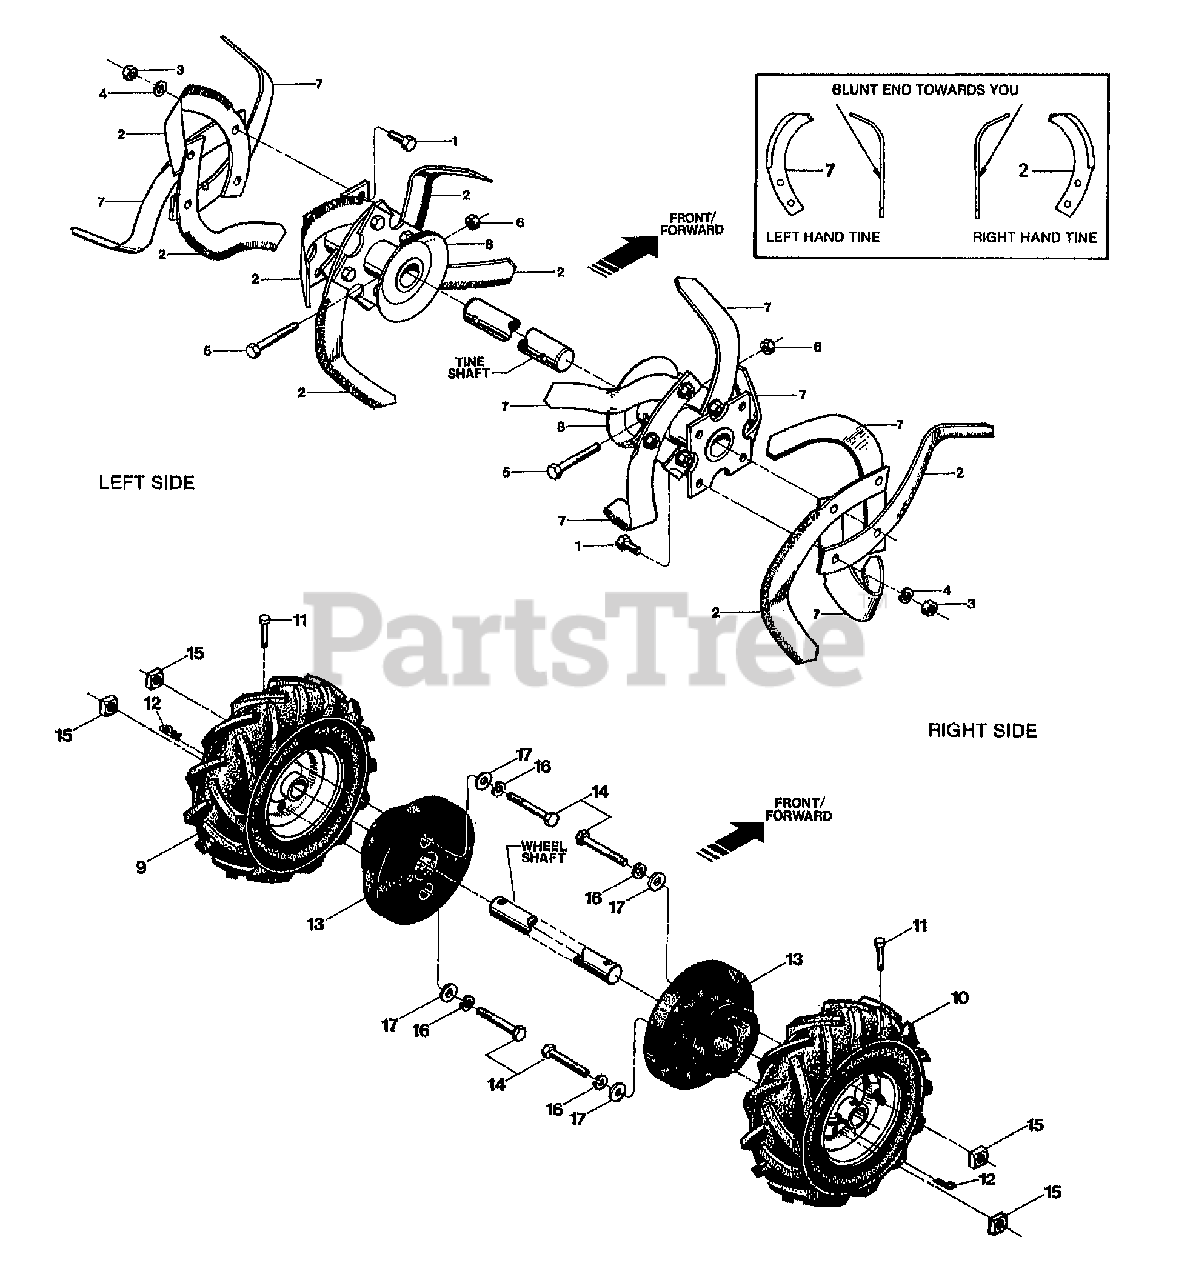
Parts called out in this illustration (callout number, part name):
1	SCR-HH 3/8-16X1.0 G5 ZP
2	TINE-BOLO RT W/HDW
3	NUT-HEX 3/8-16 ZP
4	WASHER-LK .375 @ DEPL
5	SCR-HH 3/8-16X2.00 G8
6	NUT-H/LK 3/8-16
7	TINE-BOLO LT W/HDW
8	WELD-TINE HOLDER ECONO
9	ASSM-WHEEL TIRE LT (15-20 LBS. AIR REQ'D)
10	ASSM-WHEEL TIRE RT (15-20 LBS. AIR REQ'D)
11	PIN-CLEVIS
12	PIN-CLIP .08
13	WEIGHT-WHEEL
14	SCR-HH 3/8-16X3.75
15	NUT-SQ 3/8-16
16	WASHER-LK .375 @ DEPL
17	WASHER-FLAT 3/8 SAE
